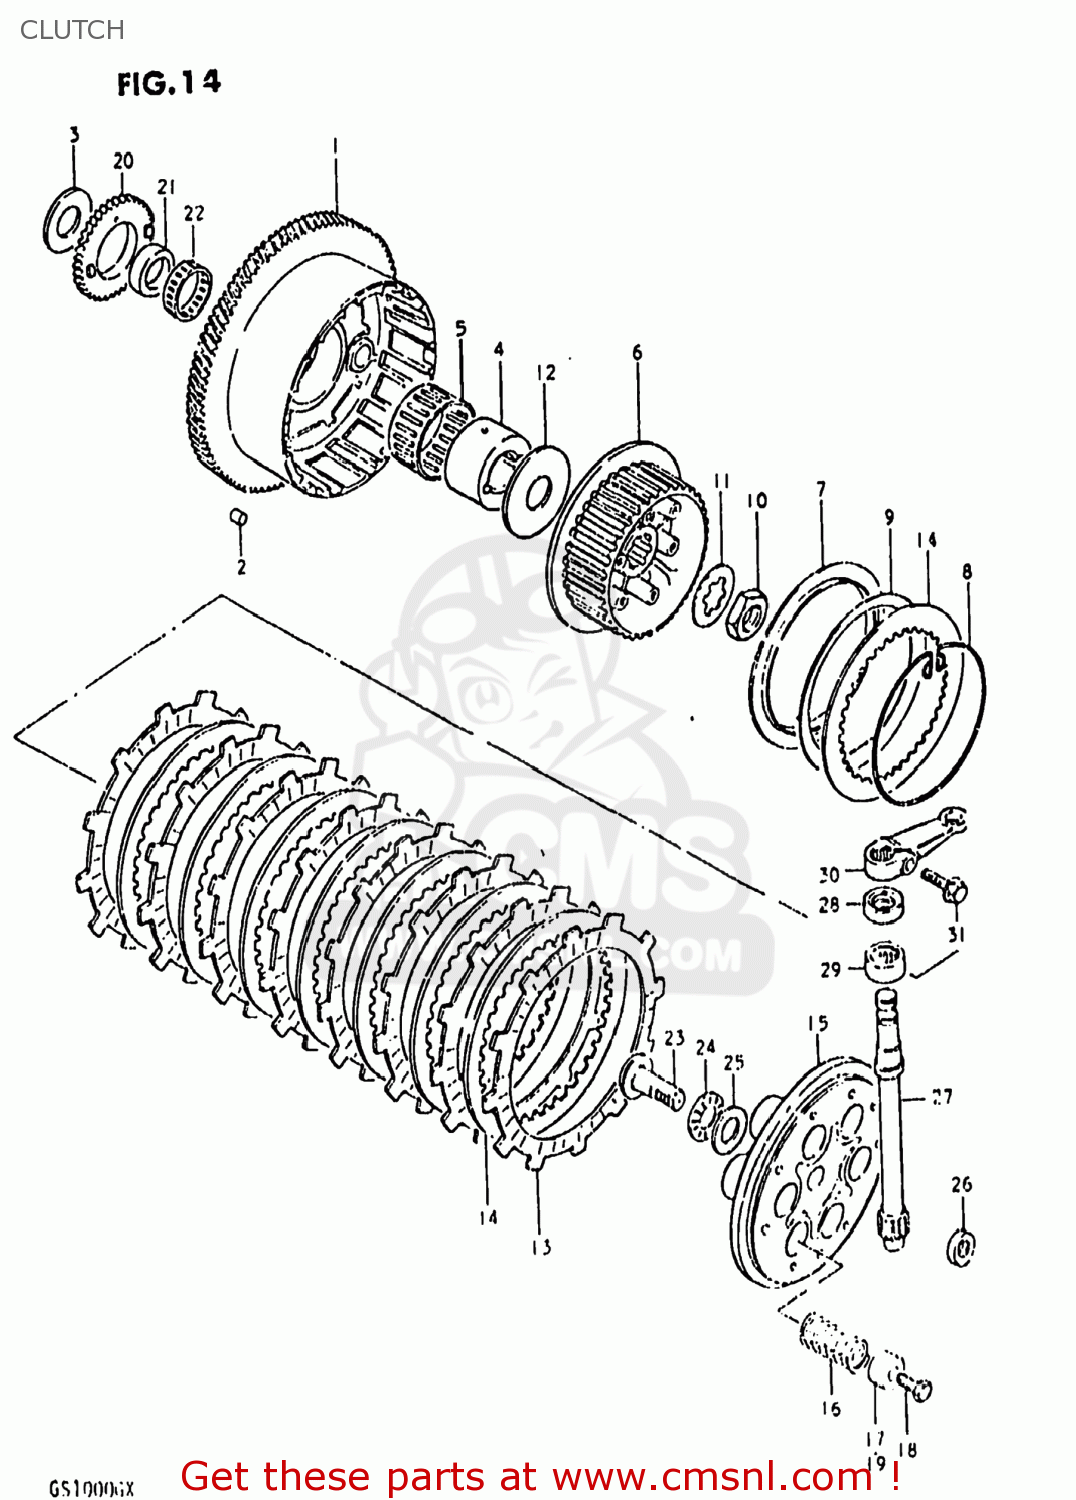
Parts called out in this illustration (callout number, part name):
1	GEAR ASSEMBLY,PRIMARY DRIVE
2	CUSHION,PRIMARY DRIVEN GEAR
3	WASHER
4	SPACER,PRIMARY DRIVEN
5	BEARING
6	HUB,CLUTCH SLEEVE
7	SEAT,WAVE WASHER
8	RING,STOPPER
9	WASHER
10	NUT
11	WASHER,LOCK
12	WASHER(25X66X3.5)
13	PLATE,CLUTCH DRIVE (MCA)
14	PLATE,CLUTCH DRIVEN (NAS)
15	PLATE,CLUTCH PRESSURE
16	SPRING
17	SPACER
18	BOLT
19	WASHER
20	GEAR,OIL PUMP DRIVE
21	SPACER,OIL PUMP DRIVE GEAR
22	BEARING(36X40X10)
23	RACK,CLUTCH RELEASE
24	BEARING(15X28X2)
25	WASHER
26	SEAL,OIL(10X16X5)
27	PINION,CLUTCH RELEASE
28	OIL SEAL
29	BEARING(15X22X12)
30	ARM,CLUTCH RELEASE
31	BOLT,REAR
